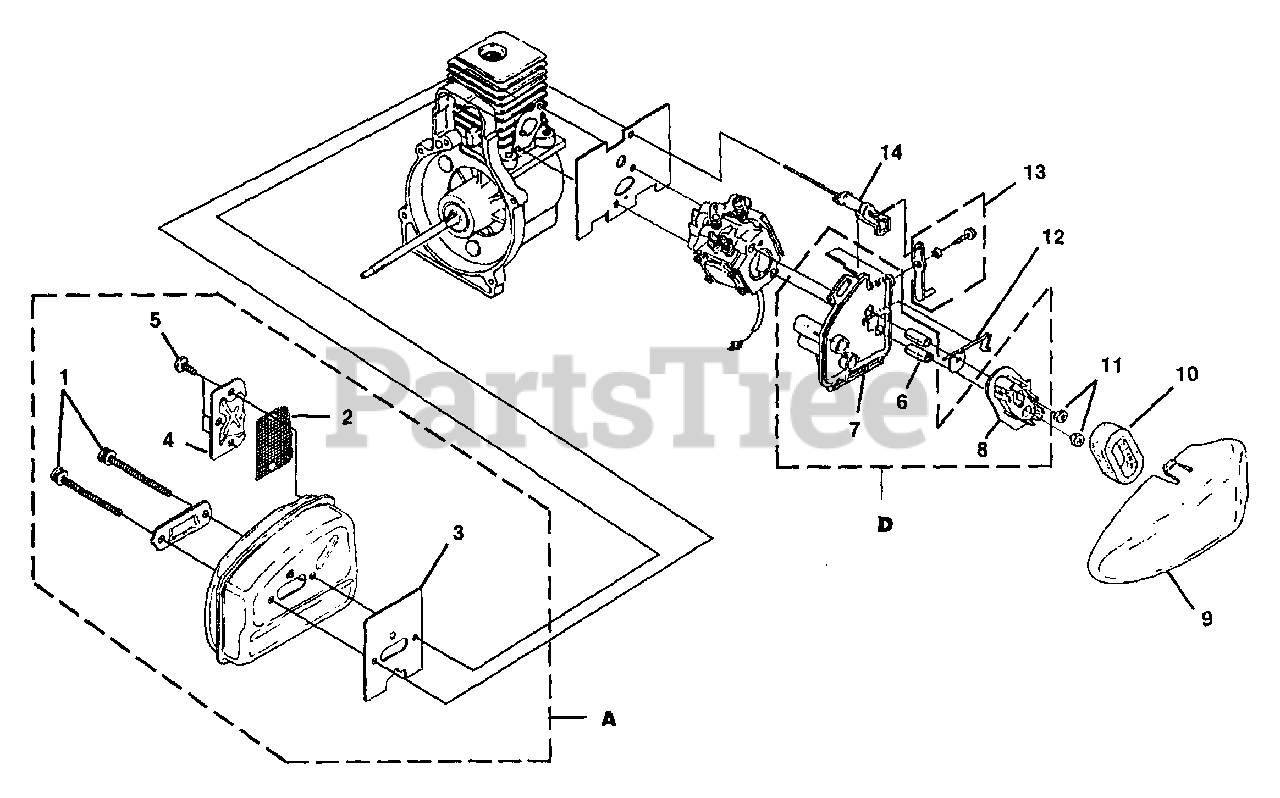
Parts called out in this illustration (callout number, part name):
1	SCREW-Machine (#10-24 X 2.188")
2	SCREEN-Spark
3	GASKET-Muffler
4	COVER
5	SCREW (8-32 x 3/8")
8	BLADE RET. MAGNET
9	COVER-Air Filter
10	FILTER-Air
11	NUT-Hex (10-24)
12	BLADE & SHAFT ASSEMBLY
13	BELLCRANK
14	CHOKE ACTUATOR
A	MUFFLER KIT
D	AIR FILTER BODY
